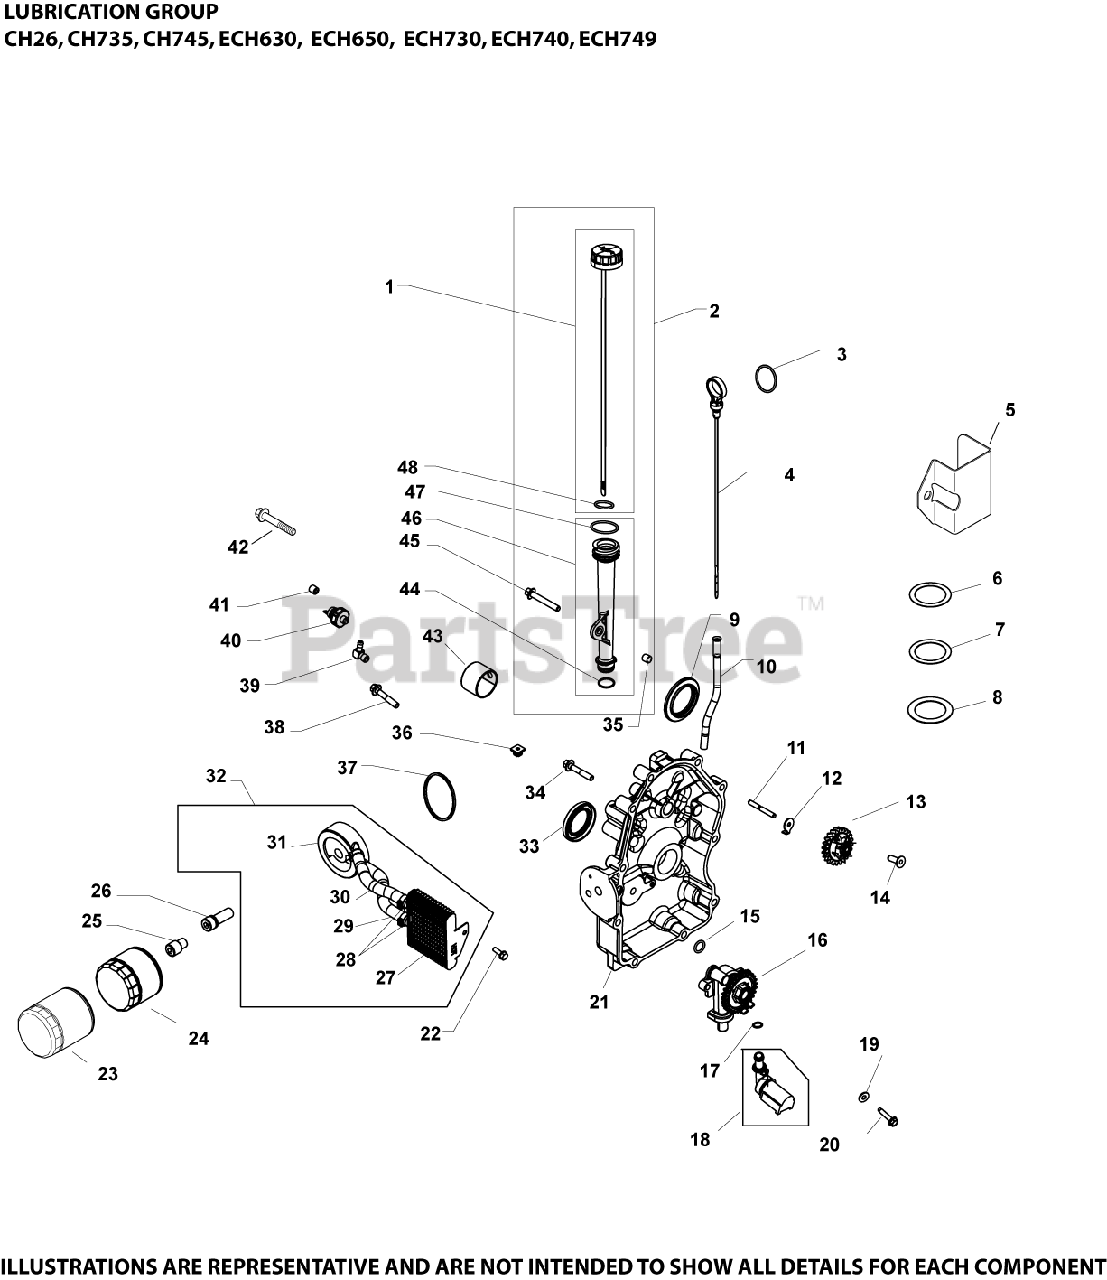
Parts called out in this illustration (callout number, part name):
10	KIT, DIPSTICK/DIPSTICK TUBES
11	SHAFT, GOVERNOR GEAR
12	TAB, LOCKING
13	KIT, GOVERNOR GEAR W/PIN
14	PIN, GOVERNOR REGULATING
16	KIT, OIL PUMP ASSEMBLY
17	O-RING, OIL PICK-UP
18	PICK-UP, OIL
19	WASHER, FLAT 1/4" (O.D. 5/8")
20	SCREW, THREAD FORMING
21	PLATE, CLOSURE & BEARING - DISCONTINUED
22	SCREW, TAP M6X1.7X18
23	OIL FILTER
26	NIPPLE, OIL FILTER
27	COOLER, OIL ASSEMBLY
28	CLAMP, HOSE LOW PROFILE
29	HOSE, OIL COOLER
30	HOSE, OIL COOLER
31	ADAPTER, OIL FILTER (CH EFI)
32	COOLER, OIL & DIVERTER ASSEMBLY USE 24 594 58-S
33	SEAL, OIL
34	SCREW - DISCONTINUED
35	PLUG, CTSK PIPE 1/8"
36	NUT, PLASTIC - BLACK
37	O-RING, OIL COOLER
38	SCREW, FLG M8X1.25X45
40	SENSOR, OIL PSI
